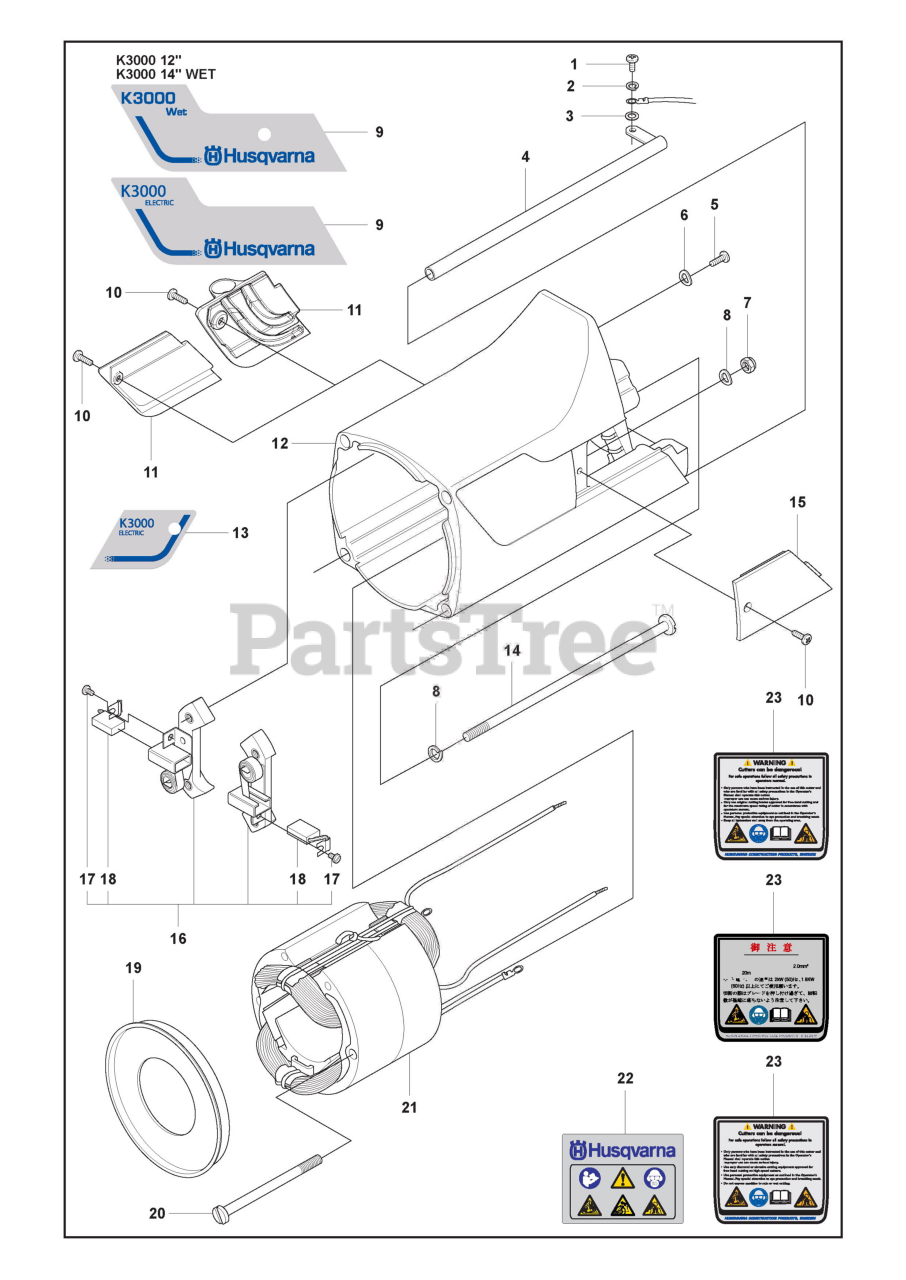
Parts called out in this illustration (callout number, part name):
9	Label
11	Lid
12	Motor Housing
16	Brush Rocker
17	Carbon Brush
19	Air Stream Director
21	Field Coil
22	Label Warning
23	Label
